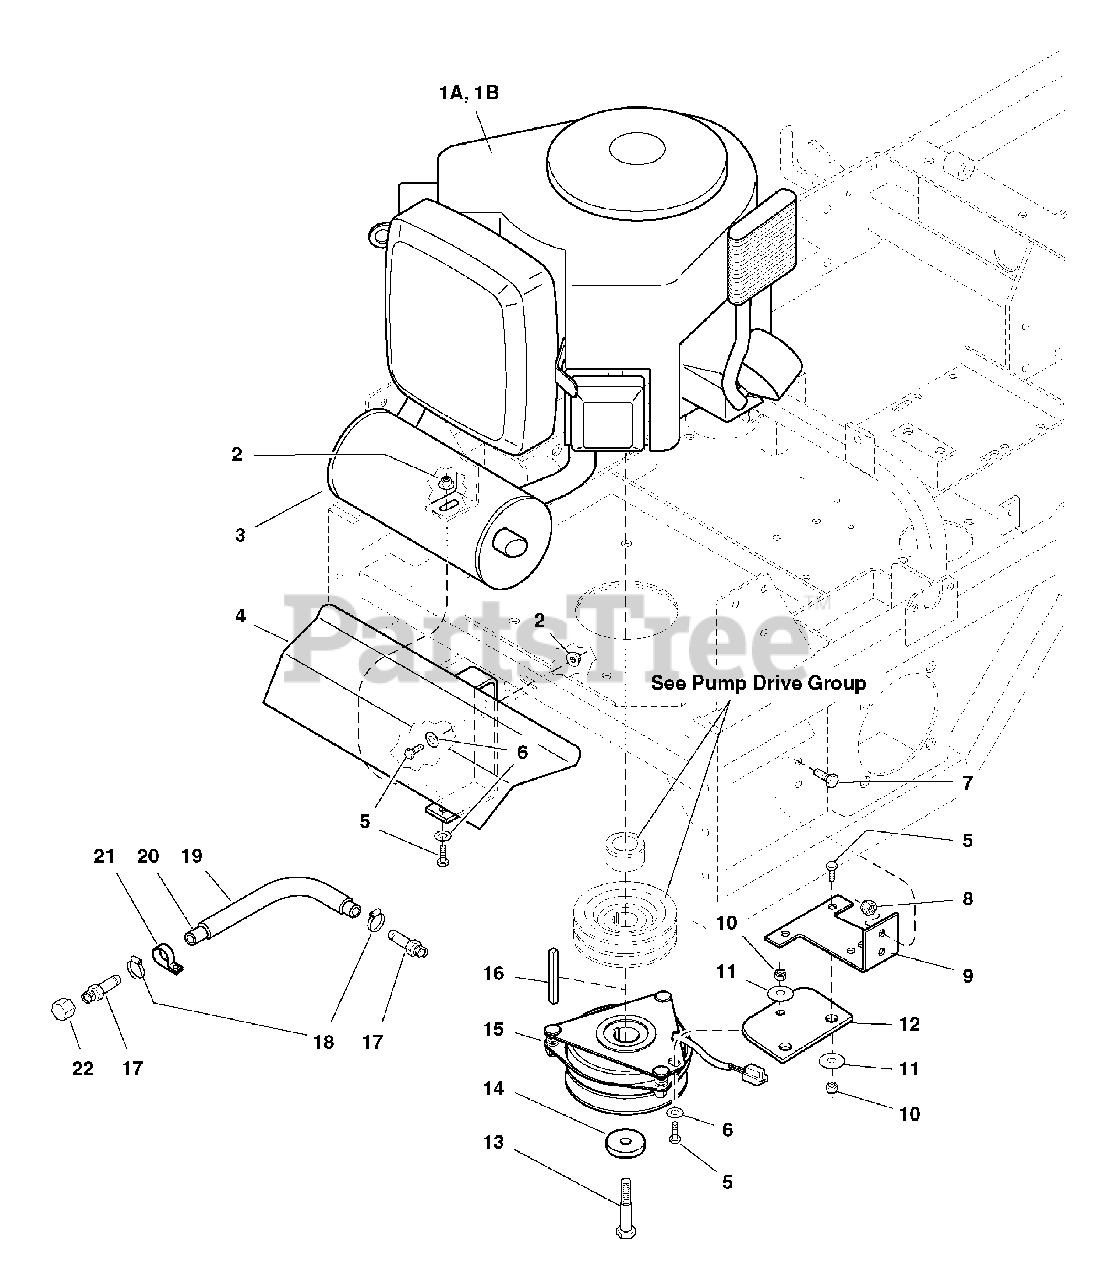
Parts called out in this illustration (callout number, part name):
1A	ENGINE, 21HP Briggs & Stratton, Model #381777
1B	ENGINE, 23HP Briggs & Stratton, Model #380777
2	NUT, Hex, Serrated Flange, 5/16-18
4	MUFFLER SUPPORT
5	CAPSCREW, Hex Hd, 5/16-18 x 3/4
6	WASHER, 5/16
7	CAPSCREW, Hex Hd, 3/8-16 x 1
8	NUT, Hex, Nylon Lock, 3/8-16
9	CLUTCH ANCHOR
10	NUT, Hex, Nylon Lock, 5/16-18
11	WASHER, Fender, 5/16
12	PAD, Clutch Anchor
13	CRANKSHAFT BOLT, 7/16 x 2
14	RETAINER, Clutch
15	ELECTRIC CLUTCH
16	KEY, 1/4 Sq. x 3
17	FITTING, 3/8NPT - 1/2 Str.
19	WIRE LOOM, 7"
20	HOSE, 9"
21	CLAMP, Vinyl
22	CAP, 3/8NPT
